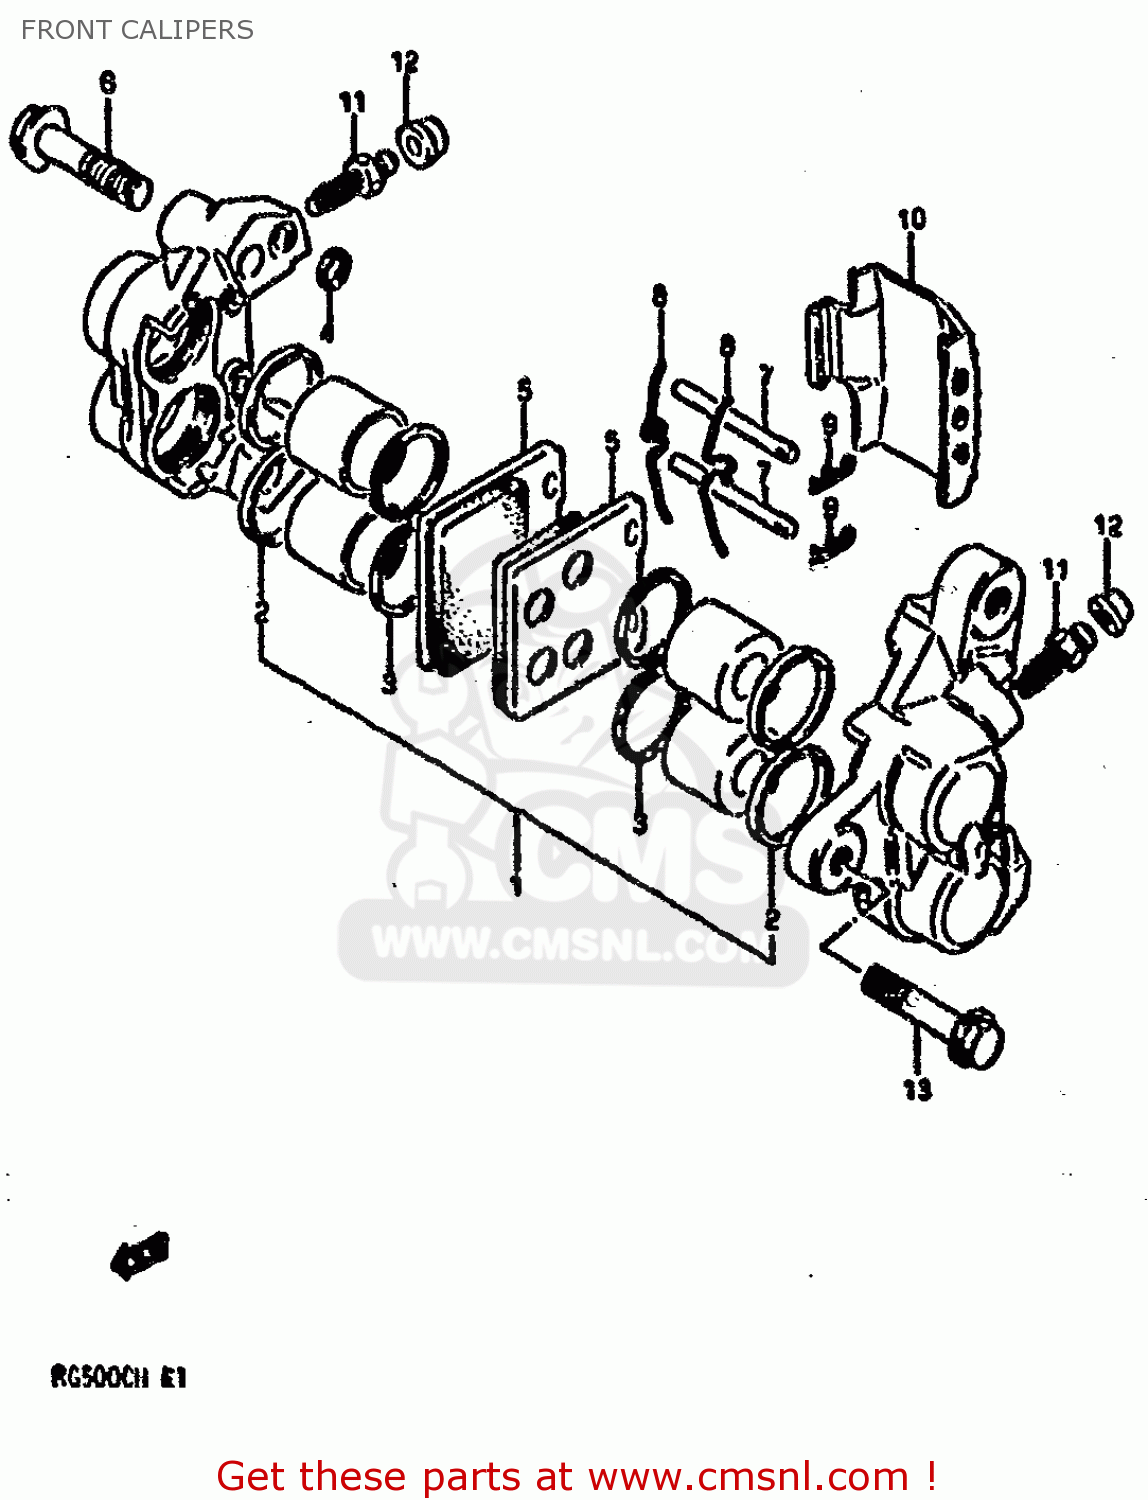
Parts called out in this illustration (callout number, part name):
1	PISTON SET
2	SEAL,PISTON
3	SEAL,WIPER
4	SEAL,JOINT
5	PAD,BRAKE (MCA)
6	BOLT,HOUSING
7	PIN,PAD
8	SPRING
9	CLIP,PAD PIN
10	COVER,CALIPER
11	BLEEDER
12	CAP,BREATHER
13	BOLT
